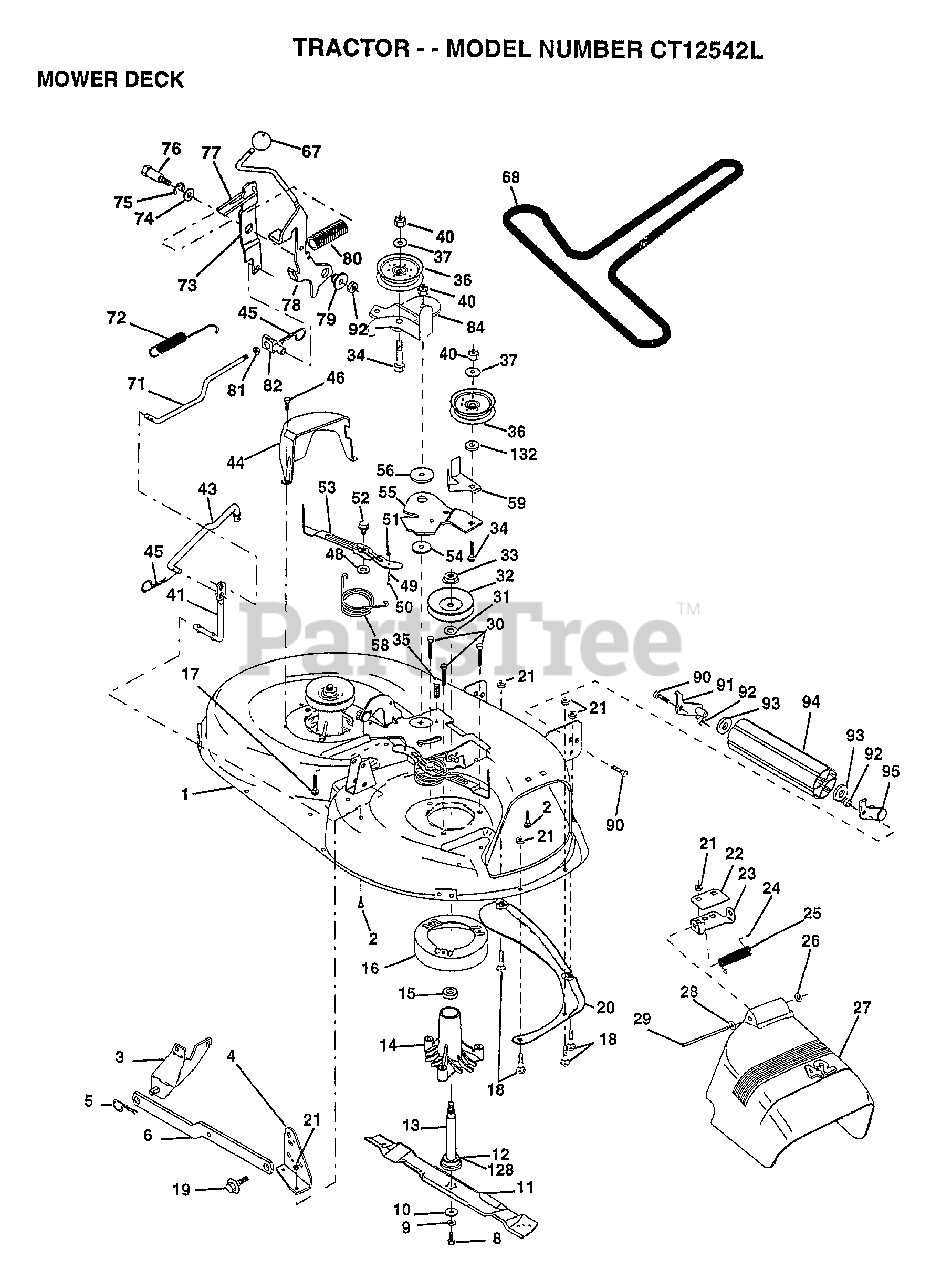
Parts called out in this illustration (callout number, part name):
1	DECK.WELD.42.
2	BOLT
3	BRKT ASM SWAY BAR
4	BRKT DECK SW BAR
8	BLADE BOLT
10	WASHER.HARD.BLADE
11	"BLADE.42"" HIPERF"
12	BEARING.BALL
14	HSG ASM MANDREL
15	BEARING
16	STRIPPER RND MWR
17	BOLT RDHD 3/8-16
18	BOLT
19	BOLT SHD 5/16-18
22	STIFFENER BRKT
23	DEFLECTOR BRKT
24	CAP-SLEEVE LT
25	SPRING TORSION
26	NUT PUSH M
27	DEFLECTOR.SHIELD
28	WASHER
29	HINGE ROD
31	WASHER
32	PULLEY.MANDREL.42
34	BOLT
35	XMAS TREE FASTNER
36	FLAT IDLER PULLEY
37	WASHER
41	PIVOT ROD
43	ROD CLUTCH W/NIBS
44	GUARD MAND LH BLK
45	RETAINER M
46	SCREW.1/4-20X5/8
48	HARD SMALL WASHER
49	ROLLER ASM-CAM
50	SHOULDER BOLT
51	LOCKNUT
52	BOLT.SHLD.5/16-18
53	BRAKE PAD ARM ASM
54	HARDENED WASHER
55	ARM-IDLER
56	SPACER RETAINER
58	SPRING TORSN BRAK
59	GUARD IDLER TUV
67	KNOB T(3/8 HOLE)
68	BELT-V.SEC.46.KEL
71	ROD CLUTCH 38/42
72	RETURN SPRING
73	CLUTCH ARM SECOND
74	WASHER
75	RING
76	SHOULDER BOLT
77	SPRING KEEPER
78	LEVER ASM-CLUTCH
79	BUSHING
80	SPRING.CLUTCH.MWR
81	NUT
82	TRUNION ADJ
84	BRACKET ASM IDLER
90	BOLT
92	NUT
93	WASHER
128	WASHER.FELT.
132	WASHER GT
